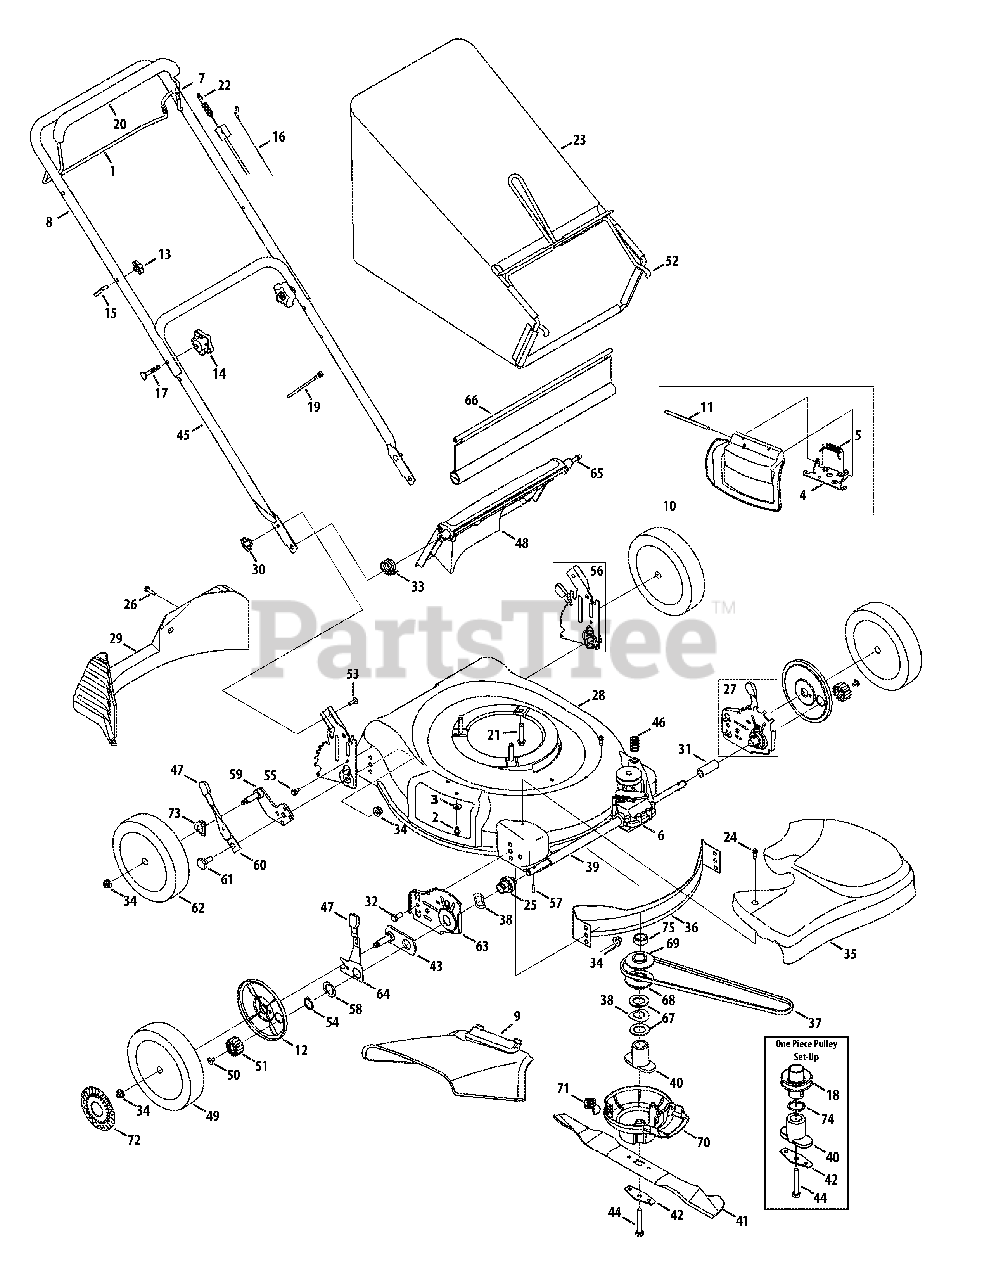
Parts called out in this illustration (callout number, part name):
1	Drive Control
2	TT Screw 1/4-20 x 0.5
3	Bell Washer.265 x 0.75
4	Deflector Chute Adapter
5	Torsion Spring
6	Transmission Assembly
7	Blade Control
8	Upper Handle
9	Chute Deflector
10	Mulch Plug Complete
11	Hinge Pin
12	Wheel Dust Cap
13	Handle Knob
14	Star Knob
15	Eye Bolt
16	Control Cable - 40.75"
16	Control Cable - 37.75"
17	Carriage Bolt 5/16-18 x 2.0
18	Pulley Assembly, Drive
19	Cable Tie
20	Bail Cover
21	Self-Tapping Sems Screw
22	Drive Cable - 51"
23	Grassbag
24	Shoulder Screw # 12 -24
25	Front Bearing Assembly
26	Screw, 1/4-15 x 1.000
27	Height Adjustment Ass’y - RH
27	Height Adjustment Ass’y - LH
29	Rear Baffle
30	Wing Nut
31	Slev. Spacer 1.4" Lg.
32	Hex Screw, 3/8-16 x.75
33	Torsion Spring - RH
34	Flange Lock Nut, 3/8-16
35	Transmission Cover - Gray
36	Front Baffle
37	V-Belt
38	Wave Washer
39	Sleeve Spacer 8.985" Lg.
40	Blade Adapter, 25mm
41	21" Mulching Blade
42	Blade Bell Support
43	Pivot Plate Assembly
44	Hex Screw 3/8-24 x 2.50
45	Lower Handle
46	Belt Tension Spring
47	Adjustment Knob
48	Rear Discharge Door
49	Front Wheel
50	Screw, 1/4-20 x .390
51	Gear 14T RH FWD
51	Gear 14T LH FWD
53	Carriage Bolt 1/4-20
54	Snap Ring
55	TT Scr. w/Washer 1/4-20 x.625
56	Handle Bracket Assembly - RH
56	Handle Bracket Assembly - LH
57	Dowel Pin
58	Washer
59	Pivot Arm Assembly - RH
59	Pivot Arm Assembly - LH
60	Rear Spring Lever
61	Shoulder Scr.500 Dia. x.434
62	Rear Wheel
63	Height Adjuster Plate - RH
63	Height Adjuster Plate - LH
64	Front Lever - RH
64	Front Lever - LH
65	Pivot Rod
66	Rear Trailing Shield
67	Washer, Flat, 1.031 x 1.620 x .095
68	Pulley, Half
69	Pulley, Half
70	Engine Baffle
71	Engine Baffle Bracket
72	Hub Cap
73	Washer, Wave, .510 x .750 x .017
74	Wave Washer
75	Sleeve Spacer
